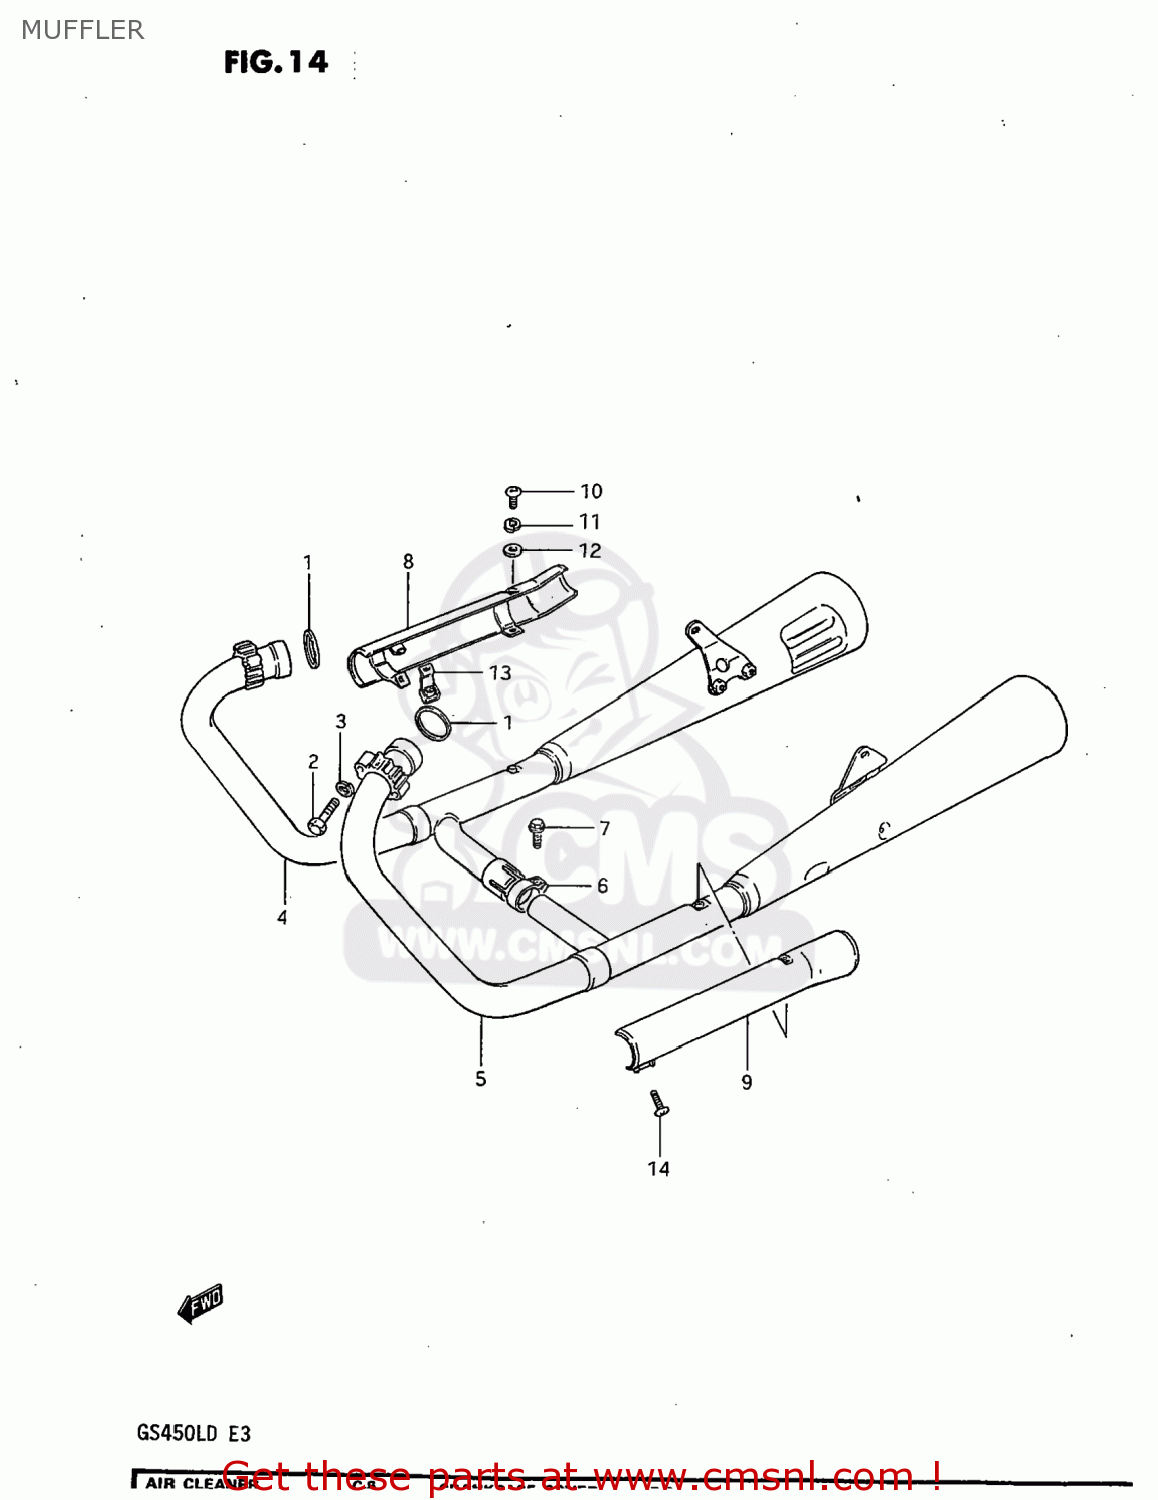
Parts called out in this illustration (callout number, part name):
1	GASKET,EXHAUST PIPE (NAS)
2	BOLT 8X40
3	LOCK WASHER
4	MUFFLER ASSEMBLY
5	MUFFLER ASSEMBLY
6	CLAMP
7	BOLT
8	COVER,MUFFLER,RIGHT
9	COVER,MUFFLER LH
10	SCREW
11	LOCK WASHER
12	WASHER
13	CLAMP,MUFFLER COVER
14	SCREW
